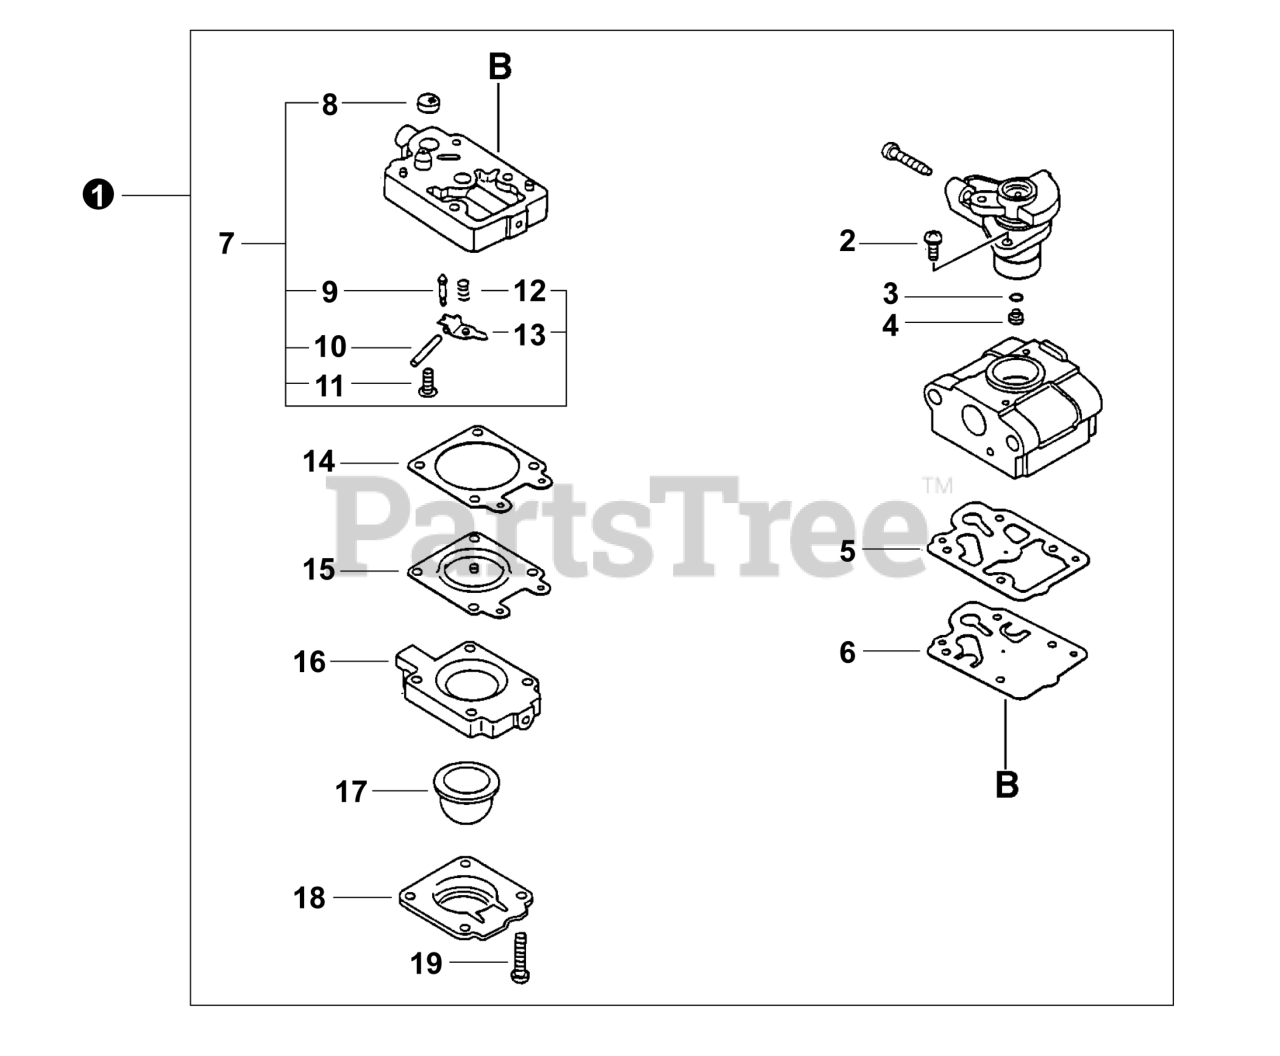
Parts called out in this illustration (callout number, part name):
1	CARBURETOR - WYL-180A
2	SCREW, THROTTLE COLLAR
3	O-RING
4	JET, MAIN
5	GASKET, FUEL PUMP
6	DIAPHRAGM, FUEL PUMP
7	BODY ASSY, PUMP
8	SCREEN, FUEL INLET
9	VALVE, INLET NEEDLE
10	PIN, METERING LEVER
12	SPRING, METERING LEVER
13	LEVER, METERING
14	GASKET, METERING DIAPHRAGM
15	DIAPHRAGM, METERING
16	BODY ASSY, PURGE
17	BULB, PURGE
18	RETAINER, PURGE BULB
